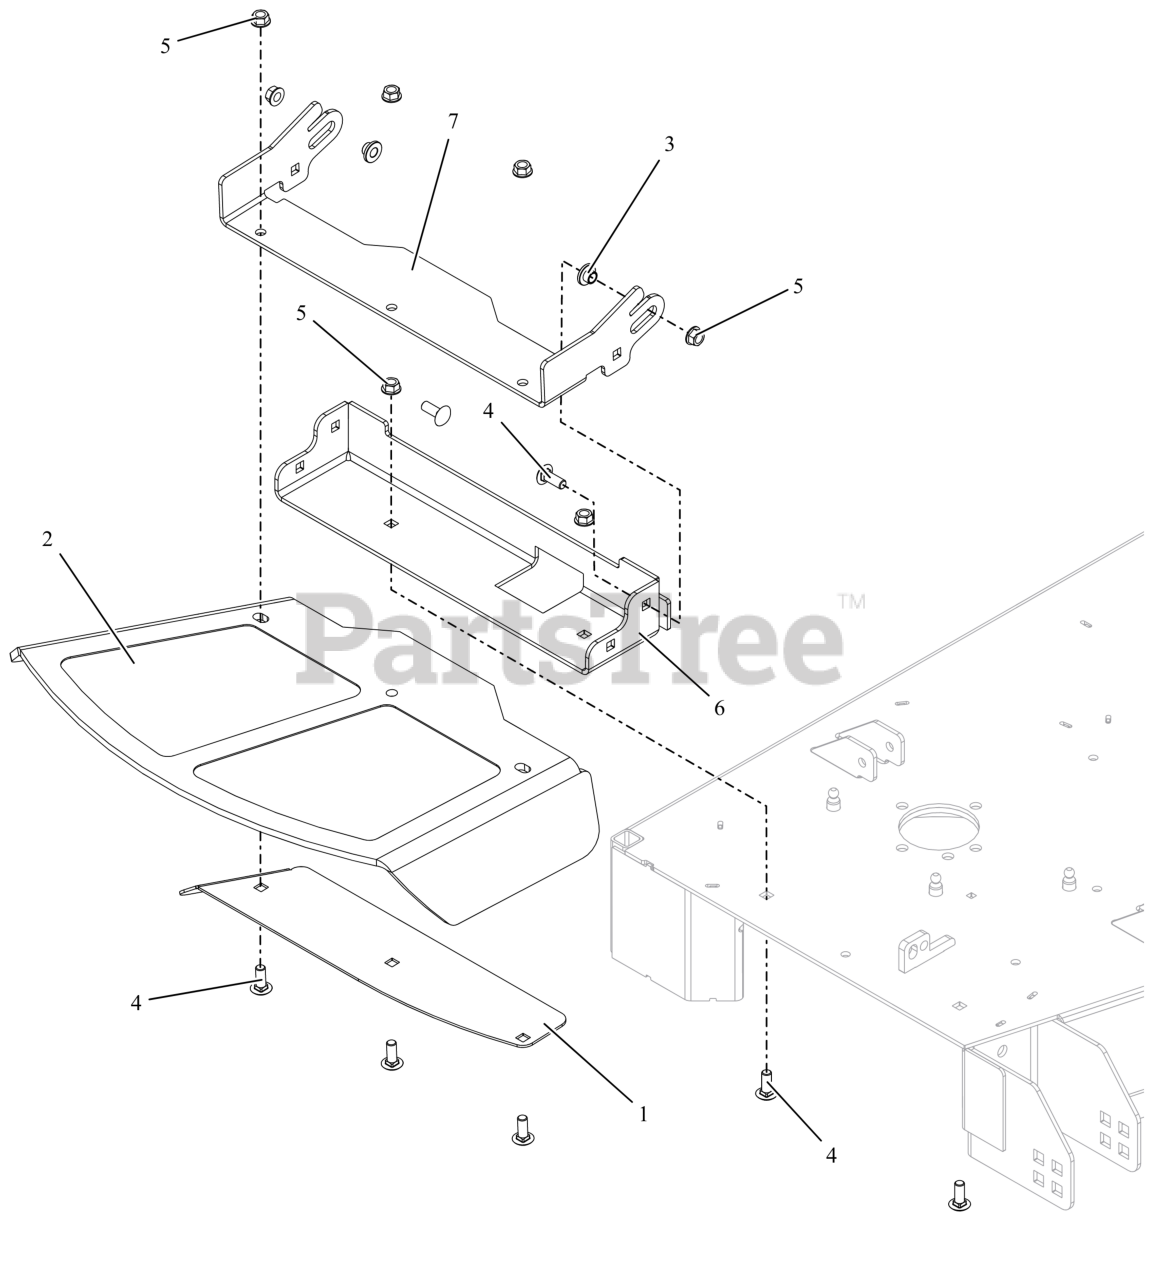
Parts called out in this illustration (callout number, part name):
1	DISCHARGE CHUTE CLMP PLT-RED
2	CHUTE, FORMED RUBBER DISCHARGE
3	BSHG-FLG .385X.500X.875X.406
4	BLT,RHSSN .38-16X1.00 G5 ZCC
5	NUT-LK-CTR-FLG .375-16 GF ZCC
6	BASE, DISCH CHUTE MTG W/SAFETY
7	BRKT- CHUTE MTG
